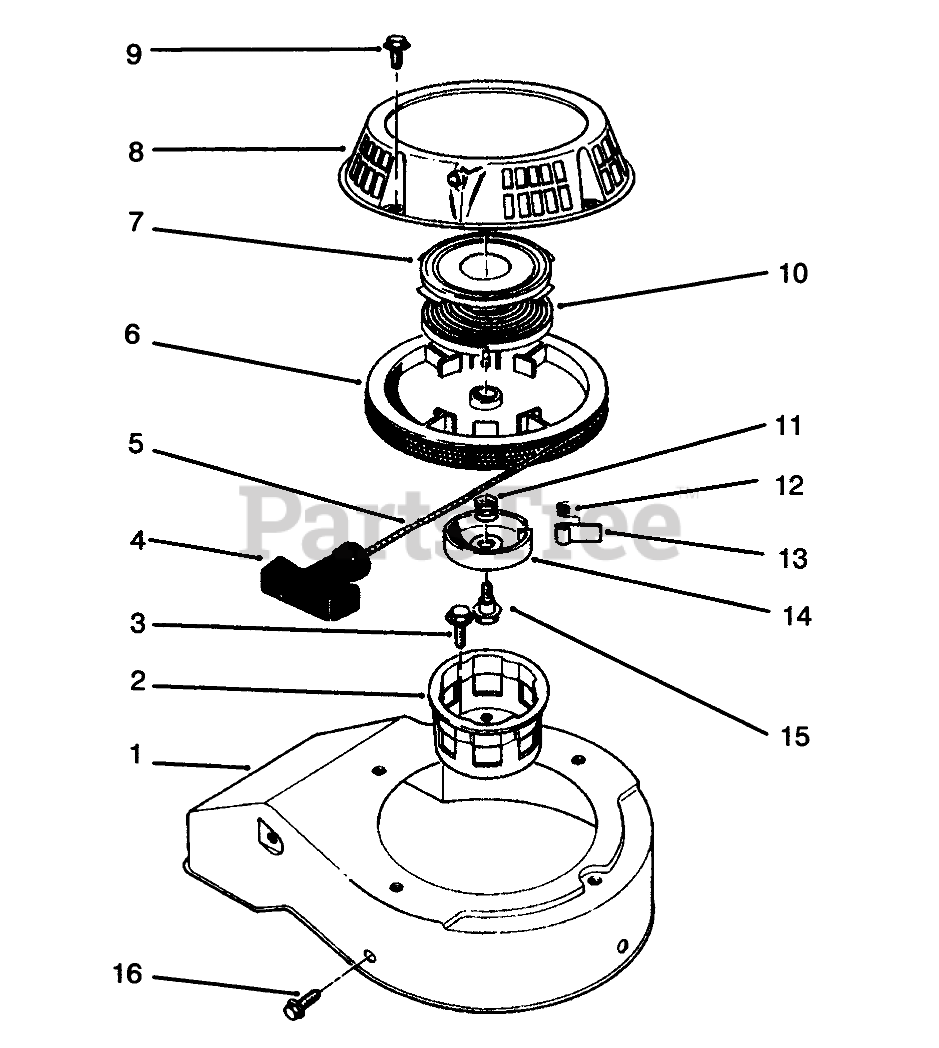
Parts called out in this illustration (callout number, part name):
1	Cover-Cooling Fan
2	PULLEY-CUP, STARTER
4	HANDLE-RECOIL
5	ROPE-STARTER
7	Retainer-Spring, Recoil
8	CASE-STARTER
9	SCREW-HHF
10	Spring-Recoil
11	SPRING
12	SPRING
14	RETAINER
